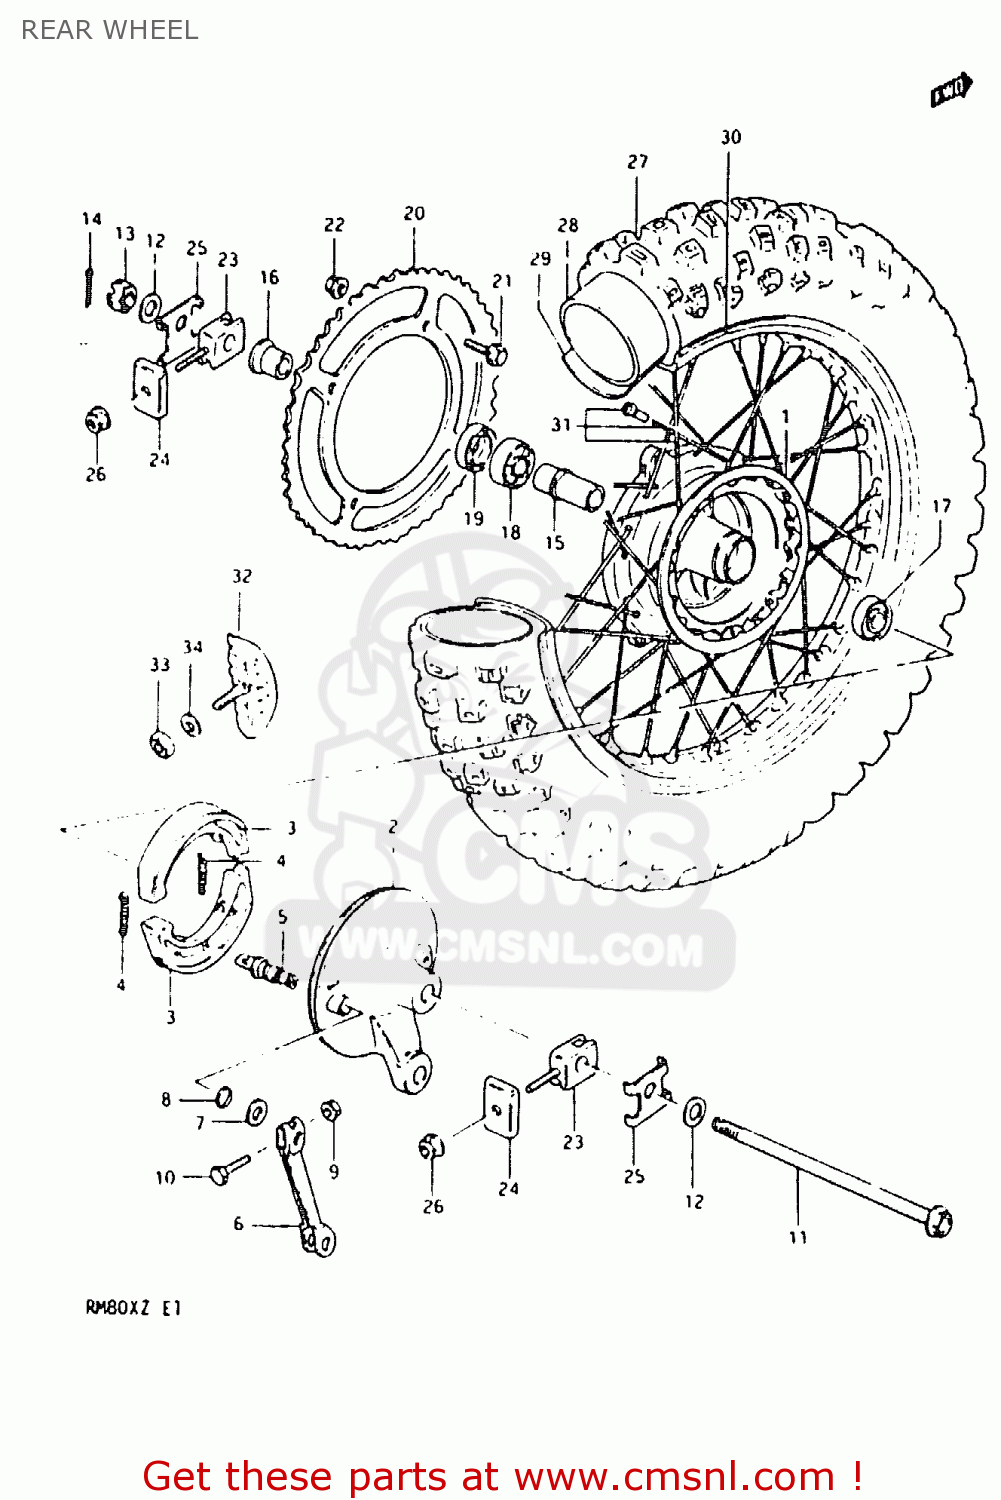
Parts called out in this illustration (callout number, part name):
1	HUB,REAR
2	PANEL,REAR HUB
3	SHOE,BRAKE
4	SPRING(L:34)
5	CAM,FRONT BRAKE
6	LEVER,RR BRAKE CAM
7	WASHER(12.5X20X1)
8	O RING(D:2.5,ID:11.4)
9	NUT
10	BOLT
11	AXLE,REAR
12	WASHER
13	NUT 12MM
14	PIN 30X20
15	SPACER,REAR HUB BEARING
16	SPACER,RR AXLE,L
17	BEARING
18	BEARING
19	OIL SEAL(17X38X5)
20	SPROCKET,REAR
21	BOLT(8X31)
22	NUT
23	ADJUSTER,CHAIN
24	ADJUSTER,CHAIN
25	WASHER,CHAIN ADJUSTER
26	NUT
27	TIRE
28	TUBE ASSEMBLY,WHEEL,INNER
29	PROTECTOR,INNER TUBE
30	RIM,REAR WHEEL
31	SPOKE SET,REAR WHEEL
32	STOPPER,BEAD
33	NUT
34	WASHER
